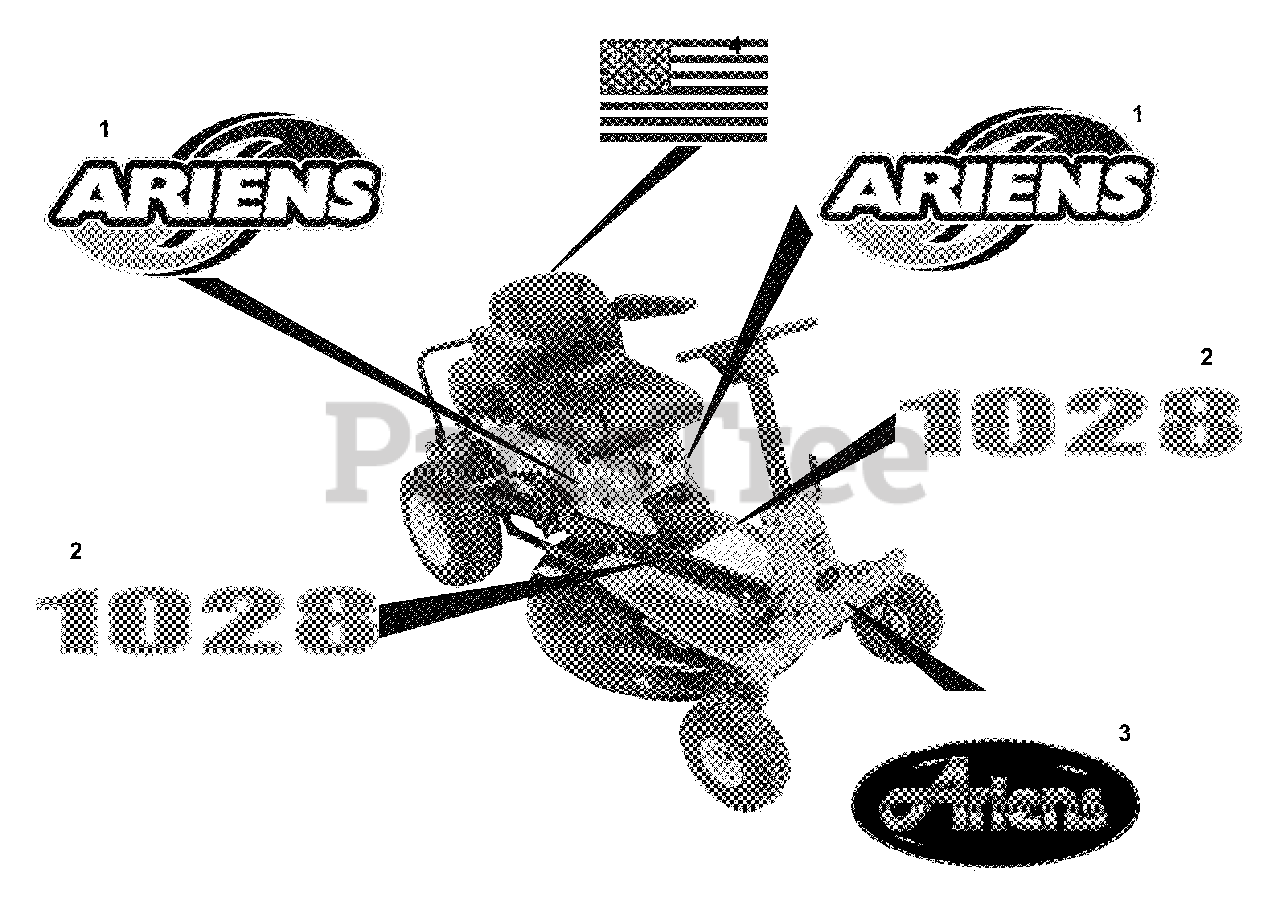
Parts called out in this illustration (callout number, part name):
1	DECAL-ARIENS ZOOM
2	DECAL-1028 RER ARIENS
2	DECAL-1232 RER ARIENS
3	DECAL-ARIENS JEWEL
4	DECAL, AMERICAN FLAG
